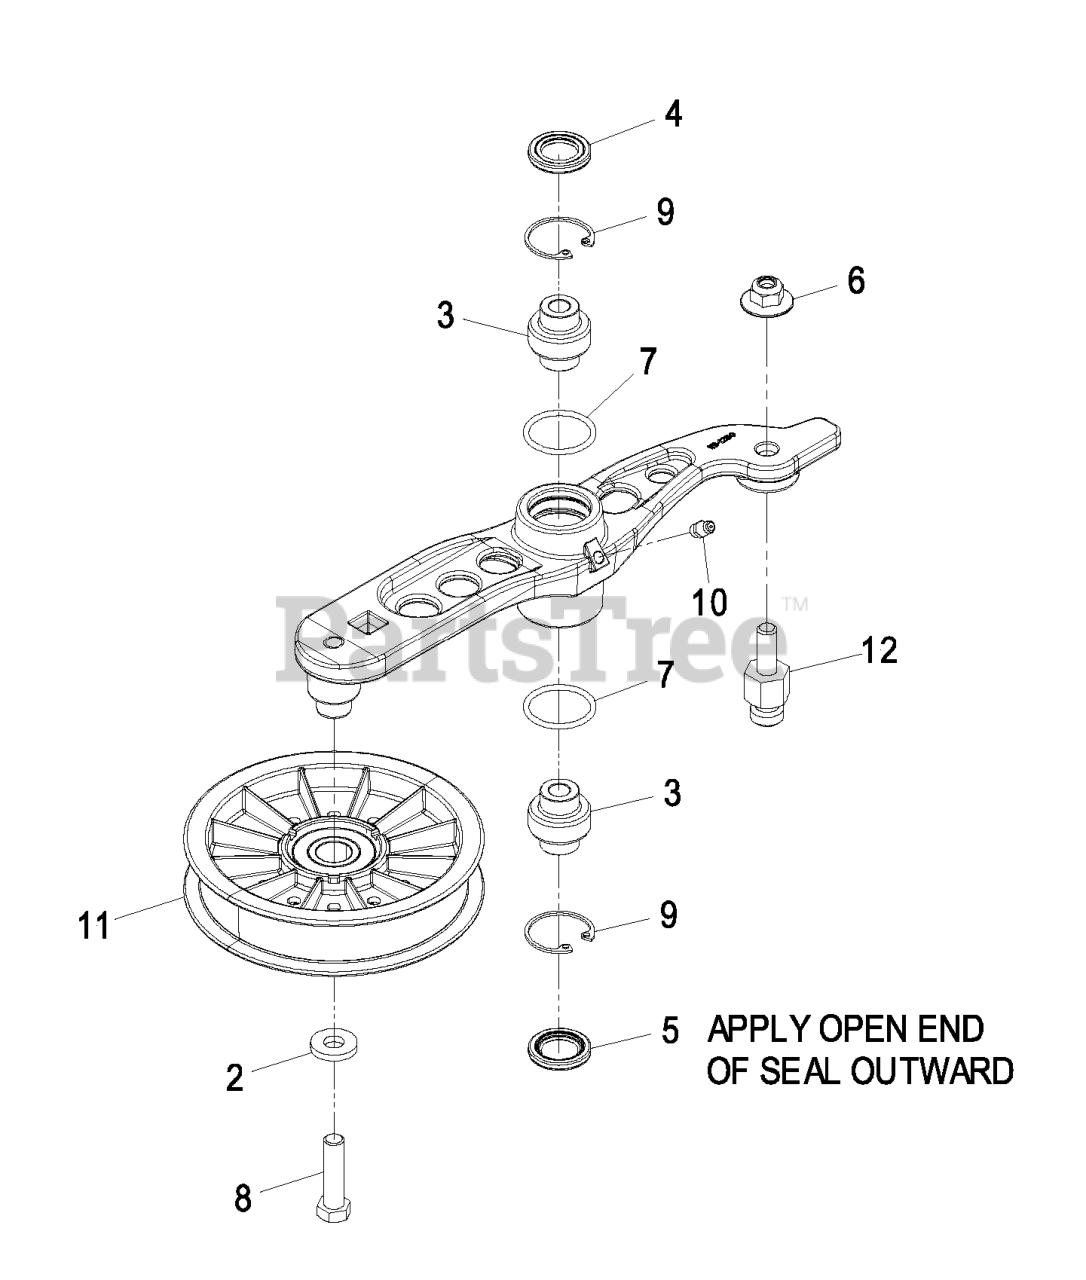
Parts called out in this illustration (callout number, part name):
3	BEARING-SPHERICAL
4	SEAL-LIP, DOUBLE
5	SEAL-LIP, SINGLE
6	Nut-Nyloc 3/8-16 Flg
8	SCREW-HH
9	RING-SNAP
10	FITTING-GREASE
11	PULLEY-IDLER
